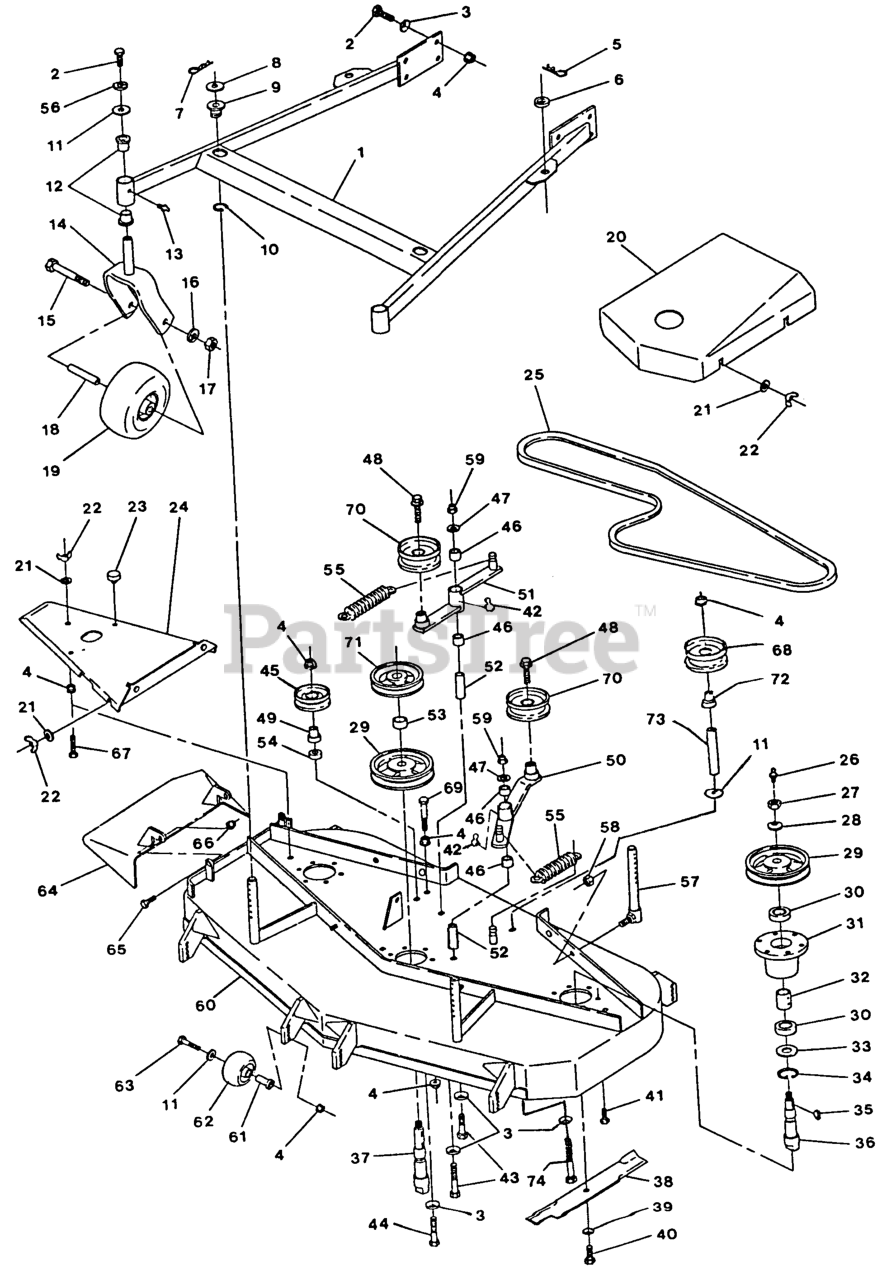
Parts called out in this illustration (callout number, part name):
5	PIN,HAIR COTTER
8	WASHER-FLAT
9	BUSHING-DECK
22	NUT-WING
24	WLD,DECK COVER
25	BELT-DRIVE, BLADE
28	WASHER-SPRING
29	SHEAVE,BLADE DRIVE
32	SPACER,BEARING
33	SEAL,MECHANICAL DUST
34	RING,SNAP WLDS N5000-244
36	SPINDLE-OUTER BLADE
37	SPINDLE-CENTER BLADE
39	WASHER-SPRING
41	SCRW,TPTTE HH
43	SCREW-HH
46	SLEEVE-BEARING
50	Arm Weldment Deck Drive Idler
51	Arm Weldment - Deck Idler
52	BUSHING-PIVOT, IDLER
53	SPACER-TUBE
55	SPRING-EXTENSION
61	BUSHING-ROLLER
62	ROLLER-SCALP, ANTI
63	SCRWCAPHH
68	PULLEY-IDLER
70	IDLER,PULLEY
72	BUSHING,IDLER
73	SPACER-FENDER
